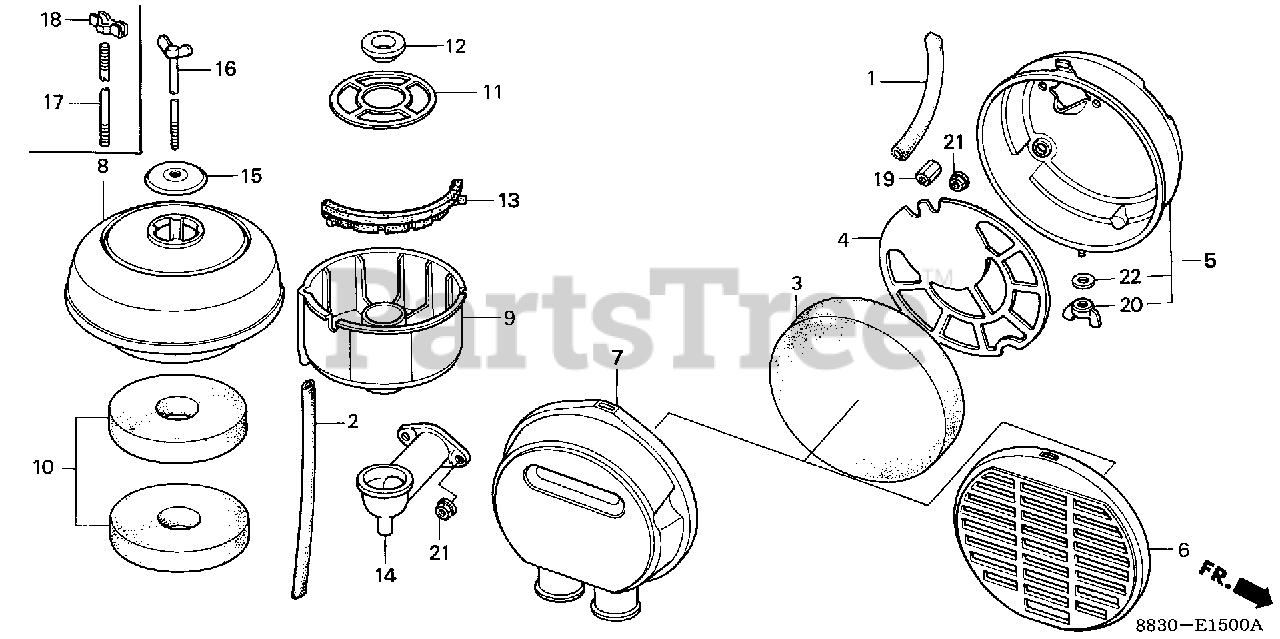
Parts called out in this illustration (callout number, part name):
1	TUBE, BREATHER Use up to Engine SN 1259988.
1	TUBE, BREATHER
3	ELEMENT, AIR CLEANER
4	GRID, AIR CLEANER
5	HOUSING, AIR CLEANER Use up to Engine SN 1259988.
5	HOUSING, AIR CLEANER
6	COVER, AIR CLEANER Use up to Engine SN 1112750.
6	COVER, AIR CLEANER
7	COVER, AIR CLEANER
19	NUT (6X15) Use from Engine SN 1298562 to 1537530.
20	NUT, TOOL BOX SETTING
21	NUT, FLANGE (6MM)
22	WASHER, PLAIN (6MM)
